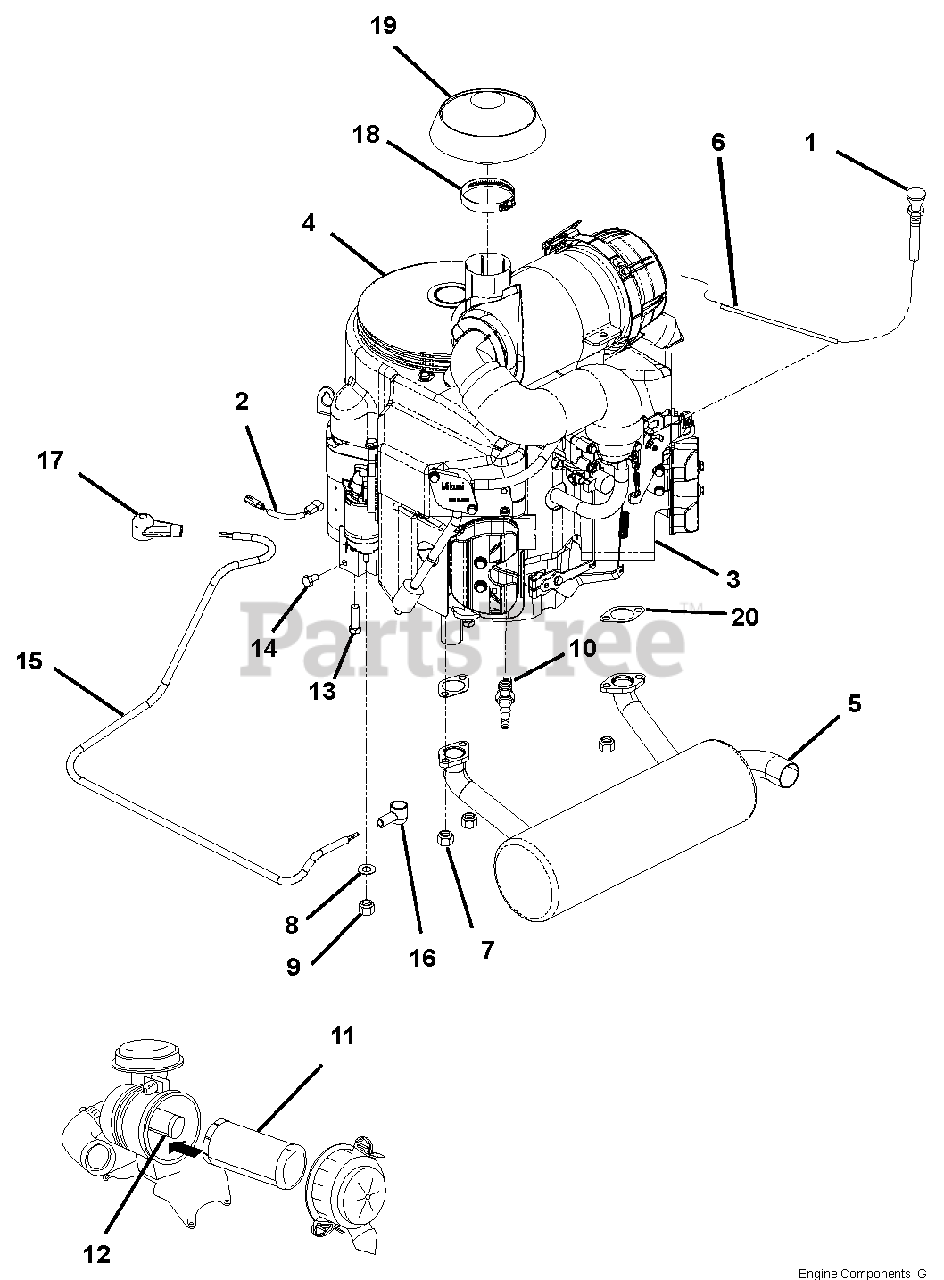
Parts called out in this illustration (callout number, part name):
1	Cable, Pro-Control Throttle (Serials 101 – 2499)
2	Lead, Starter Solenoid
3	Oil Filter
4	Engine, Kawasaki 27 HP
4	Engine, Kawasaki 31 HP
5	Muffler, Kawasaki Horizontal
6	Wire Harness, Kawasaki (see page 26-27)
7	Nut, Exhaust Man. Subaru EH
8	Washer, M8 Spring Lock
9	Nut, M8 x 1.25 Hex Grade 8.8
10	Spark Plug
11	Filter, Outer Air
12	Filter, Inner Air
13	Bolt, Hex .38-16 x 1.25 FTHG5
14	Bolt, M8 x 1.25 x 14 Hex 8.8
15	Cable, Battery- 42" Positive
16	Boot, Eyelet Terminal
17	Battery Terminal Boot, Red
18	Clamp, Hose 2.75 Diameter Worm (992222, 209)
18	Clamp, Hose 2.75 Diameter Worm (992220, 210)
19	Rain Cap, Air Cleaner (992222)
19	Rain Cap, Air Cleaner (992220, 221)
20	Gasket, Muffler S/O
